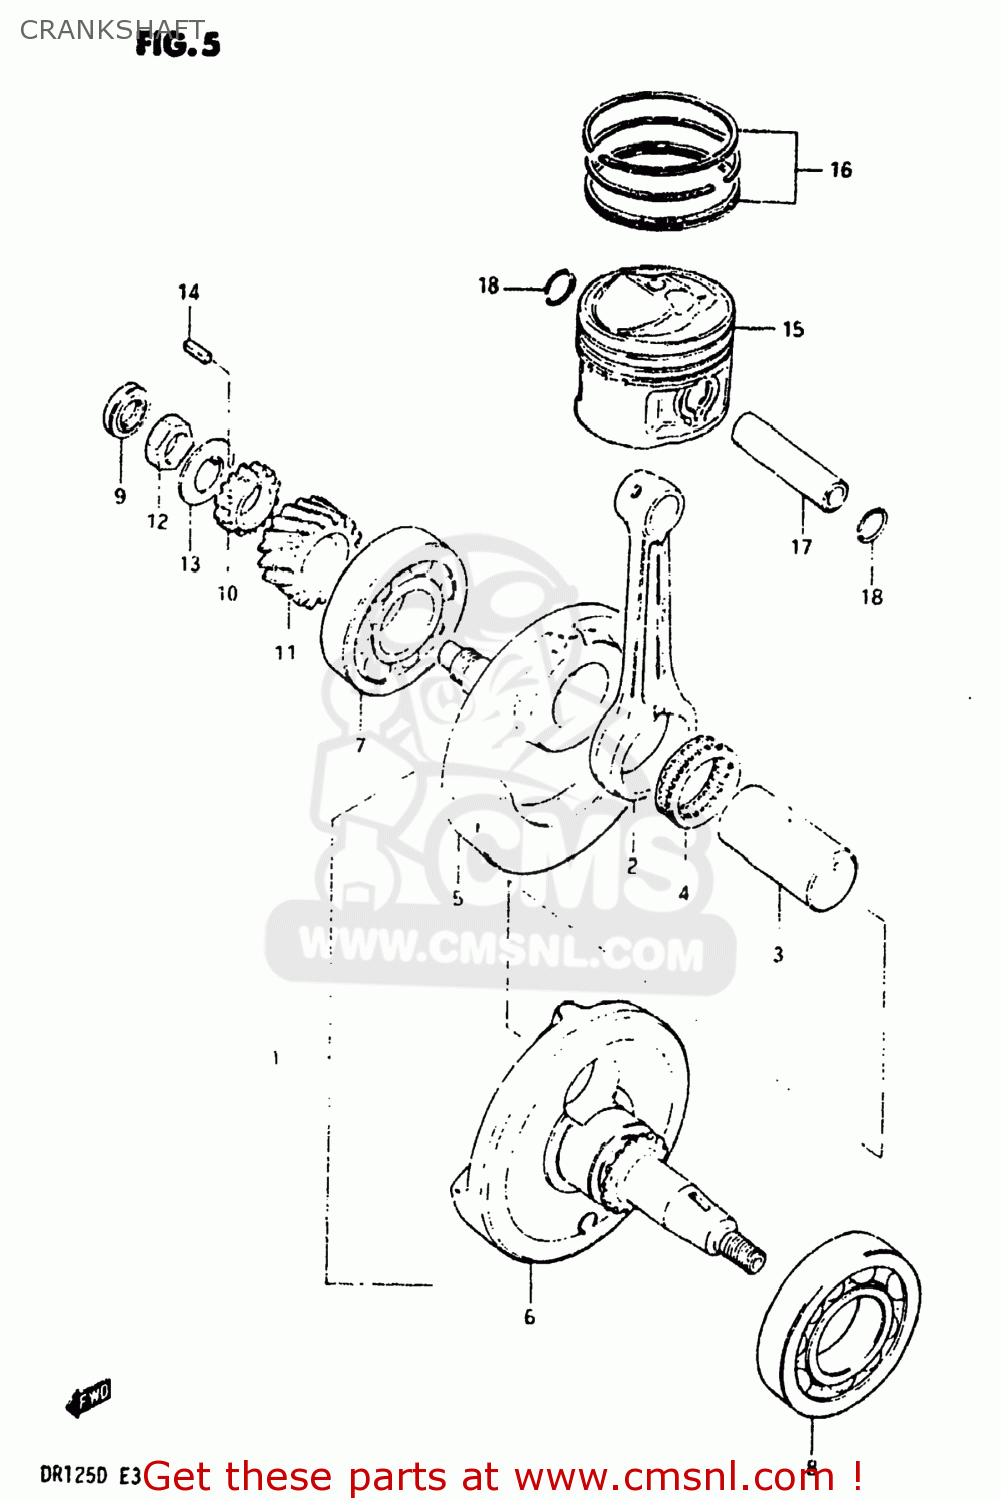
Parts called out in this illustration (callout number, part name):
1	CRANKSHAFT ASSEMBLY
2	CONNECTING ROD
3	PIN,CRANK
4	BEARING
5	CRANKSHAFT
6	CRANKSHAFT,LEFT
7	BEARING,MIDDLE
8	BEARING,LEFT
9	OIL SEAL
10	GEAR,OIL PUMP DRIVE
11	GEAR,PRIMARY DRIVE
12	NUT
13	WASHER
14	KEY
15	PISTON (STD)
16	RING SET,PISTON
17	PIN,PISTON
18	RING,SNAP 14MM
